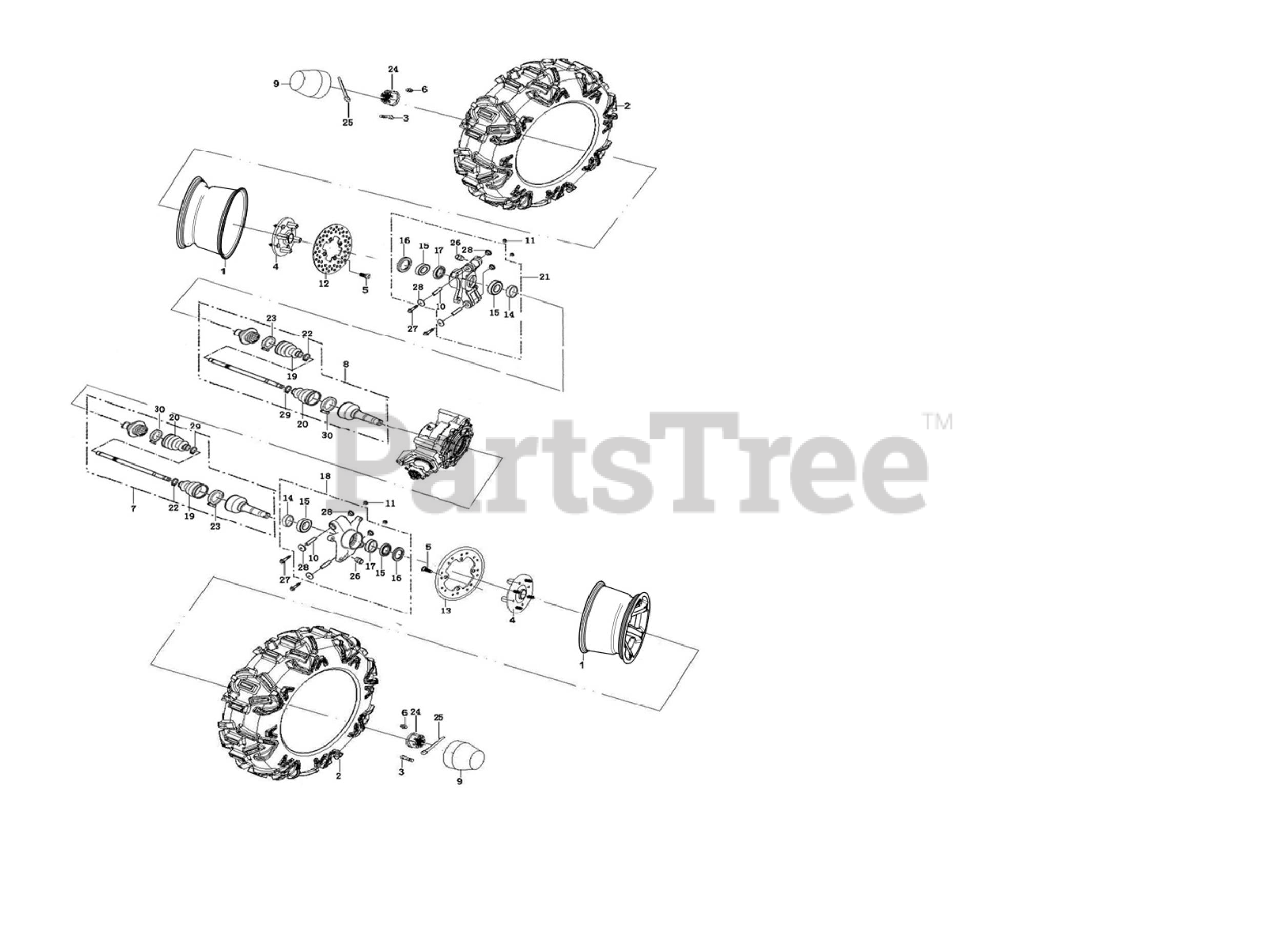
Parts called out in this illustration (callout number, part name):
1	RIM - REAR
2	TIRE RADIAL - REAR
3	valve core
4	Connecting base assy,rear hub
5	Inner hexagon cone bolt with pan M8
6	Taper nut M10x1.25
7	REAR LEFT CONSTANT VELOCITY JOINT Z
8	REAR RIGHT CONSTANT VELOCITY JOINT Z
9	DUST COVER HUB G
10	Knuckle bearing sleeve line
11	LOCK NUT M10x1.25
12	DISC BRAKE - REAR RIGHT
13	DISC BRAKE - REAR LEFT
14	Rear Knuckle inside oil seal 38x 62x8
15	BEARING 6206RS
16	Rear Knuckle outside oil seal 42x 62x7
17	REAR STEERING KNUCKLE TUBE
18	Front Left Knuckle
19	Axle rubber boot G
20	Axle Rubber boot F
21	Front Right Knuckle
22	CLAMP - LARGE BTB F
23	CLAMP - LARGE BTB E
24	SLOTTED NUT M24x1.5
25	COTTER PIN 3.2x50
26	Knuckle oil fitting
27	BOLT HExAGON FLANGE HEAD M10x1.25-110
29	CLAMP - LARGE BTB U
30	CLAMP - LARGE BTB T
